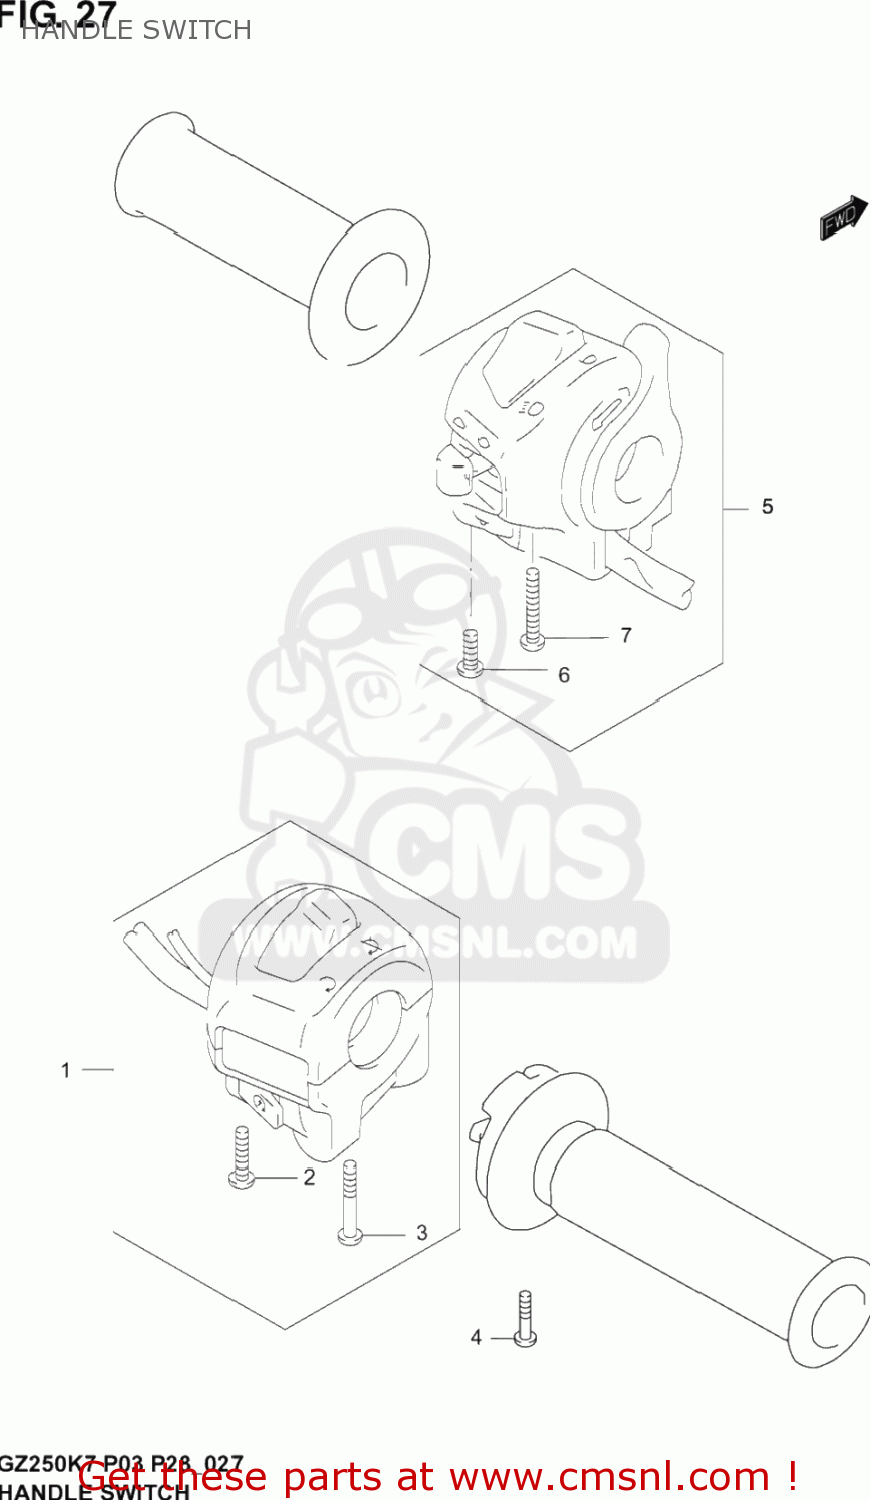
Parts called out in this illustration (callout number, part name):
1	SWITCH ASSY RH
2	SCREW
3	SCREW
4	SCREW
5	SWITCH ASSY, HANDLE LH
6	SCREW
7	SCREW
